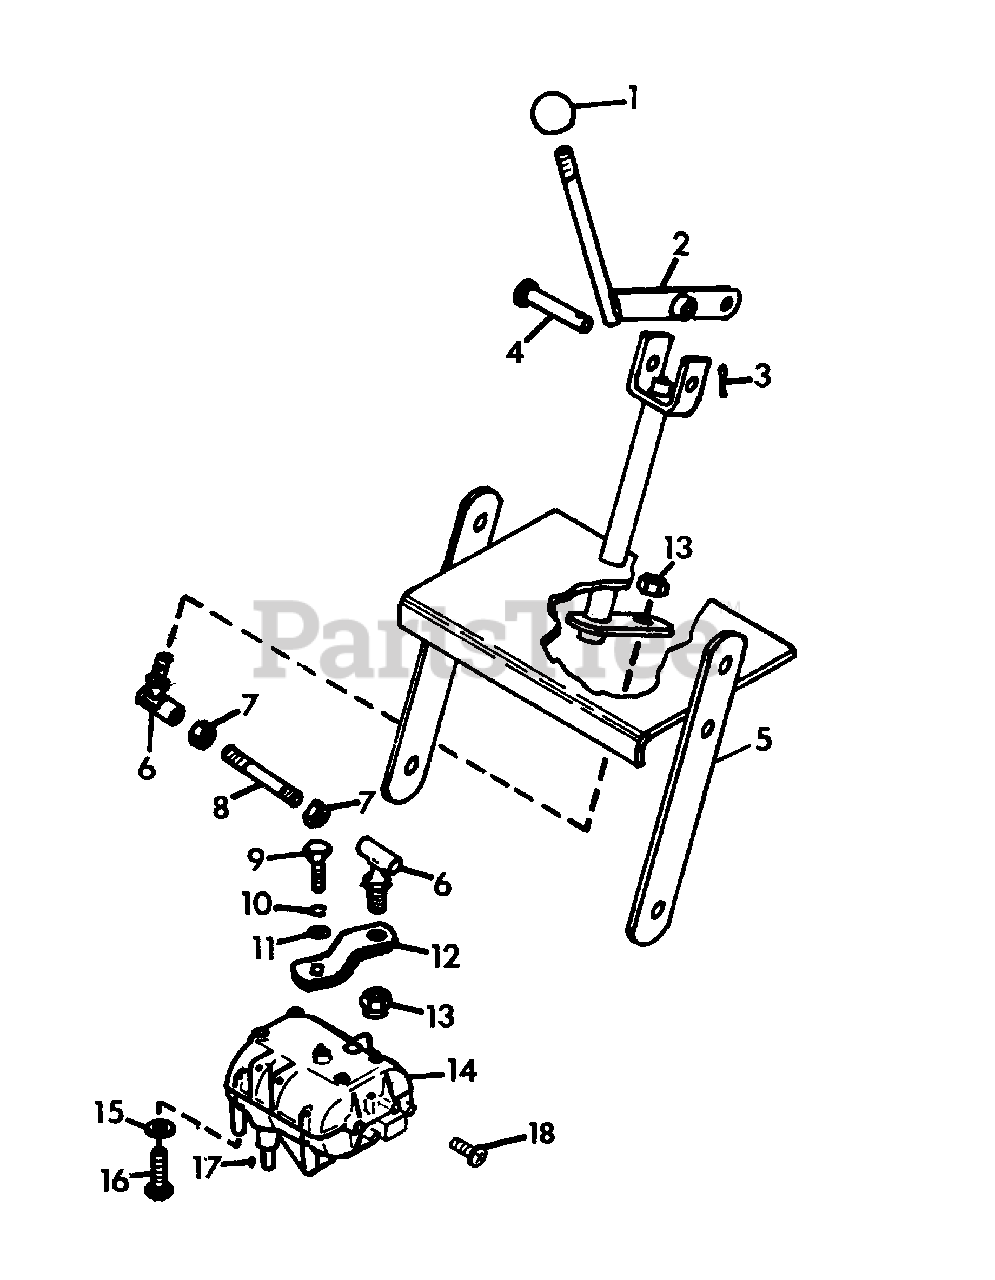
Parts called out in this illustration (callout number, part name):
1	KNOB, CONTROL
2	WELDMENT, SHIFT LEVER
3	PIN, COTTER .09X.625
4	PIN, CLEVIS
5	WELDMENT, SHIFTER
6	BALL JOINT, DISCONNECTING
7	NUT, HEX 1/4-28
8	ROD, TRANS. SHIFTER
9	BOLT, HEX 1/4-28X.50
10	WASHER, LOCK 1/4
11	WASHER, FLAT .281X.625X.065
12	ARM, TRANS. SHIFT
13	NUT, LOCK 1/4-28
14	TRANSMISSION, 5-SPEED
15	WASHER, LOCK 7/16
16	BOLT, HEX 5/16-18X.75
17	KEY, WOODRUFF .187X.750 HARD
18	SCREW, TAPPING 1/4-20X.50 P/HD
